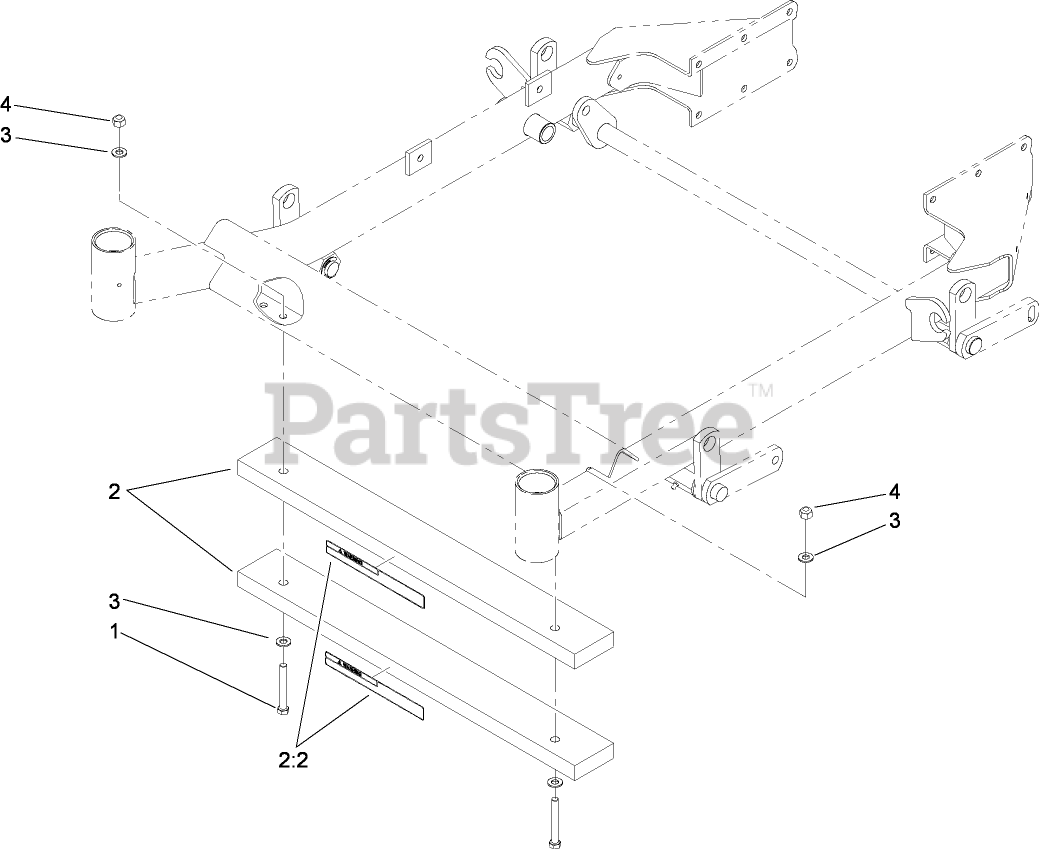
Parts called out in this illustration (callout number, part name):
1	SCREW-HH
2	WEIGHT
2:2	DECAL-WARNING, COUNTER WEIGHT
3	WASHER-FLAT
4	NUT-LOCK, NI
